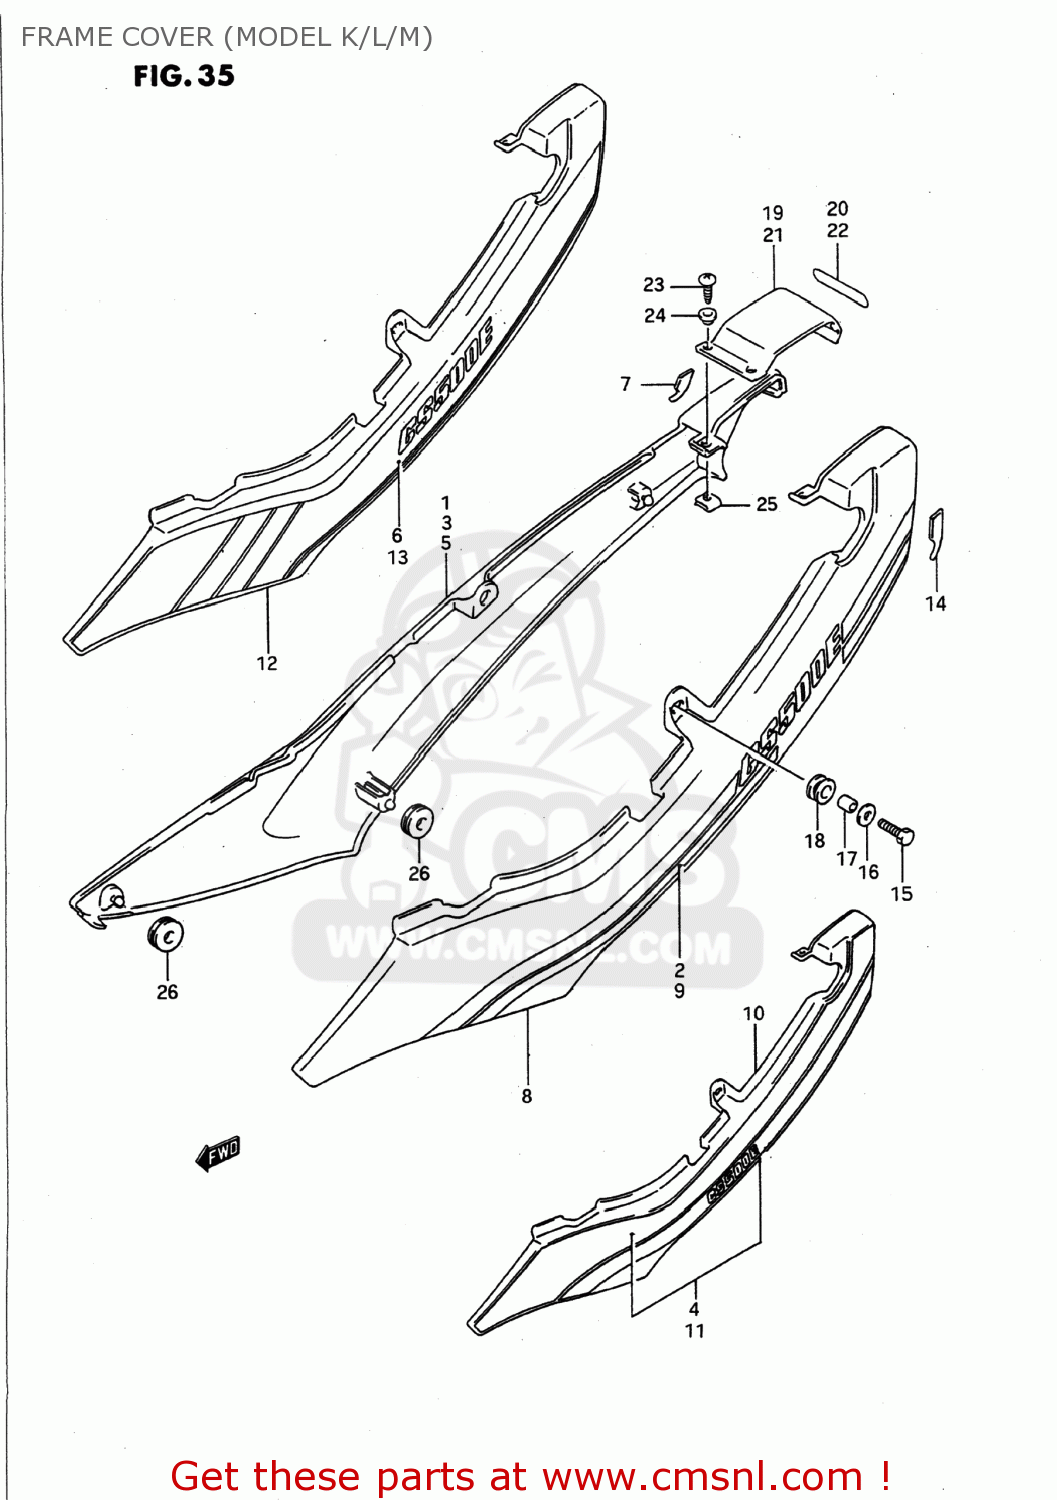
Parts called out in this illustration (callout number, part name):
1	COVER,FRAME,RIGHT
2	TAPE SET,FRAME COVER,RIGHT
3	COVER,FRAME,RIGHT
4	TAPE SET,FRAME COVER,RIGHT
5	COVER,FRAME,RIGHT
6	TAPE SET,FRAME COVER,RIGHT
7	PROTECTOR,FRAME COVER,R
8	COVER,FRAME,LEFT
9	TAPE SET,FRAME COVER,LEFT
10	COVER,FRAME,LEFT
11	TAPE SET,FRAME COVER,LEFT
12	COVER,FRAME,LEFT
13	TAPE SET,FRAME COVER,LEFT
14	PROTECTOR,FRAME COVER,L
15	BOLT(6X20)
16	WASHER
17	SPACER (6.1X9X9)
18	CUSHION
19	COVER,FRAME CTR
20	EMBLEM
21	COVER,FRAME,CENTER
22	EMBLEM
23	SCREW
24	WASHER(5.2X14X1.5)
25	NUT
26	CUSHION
